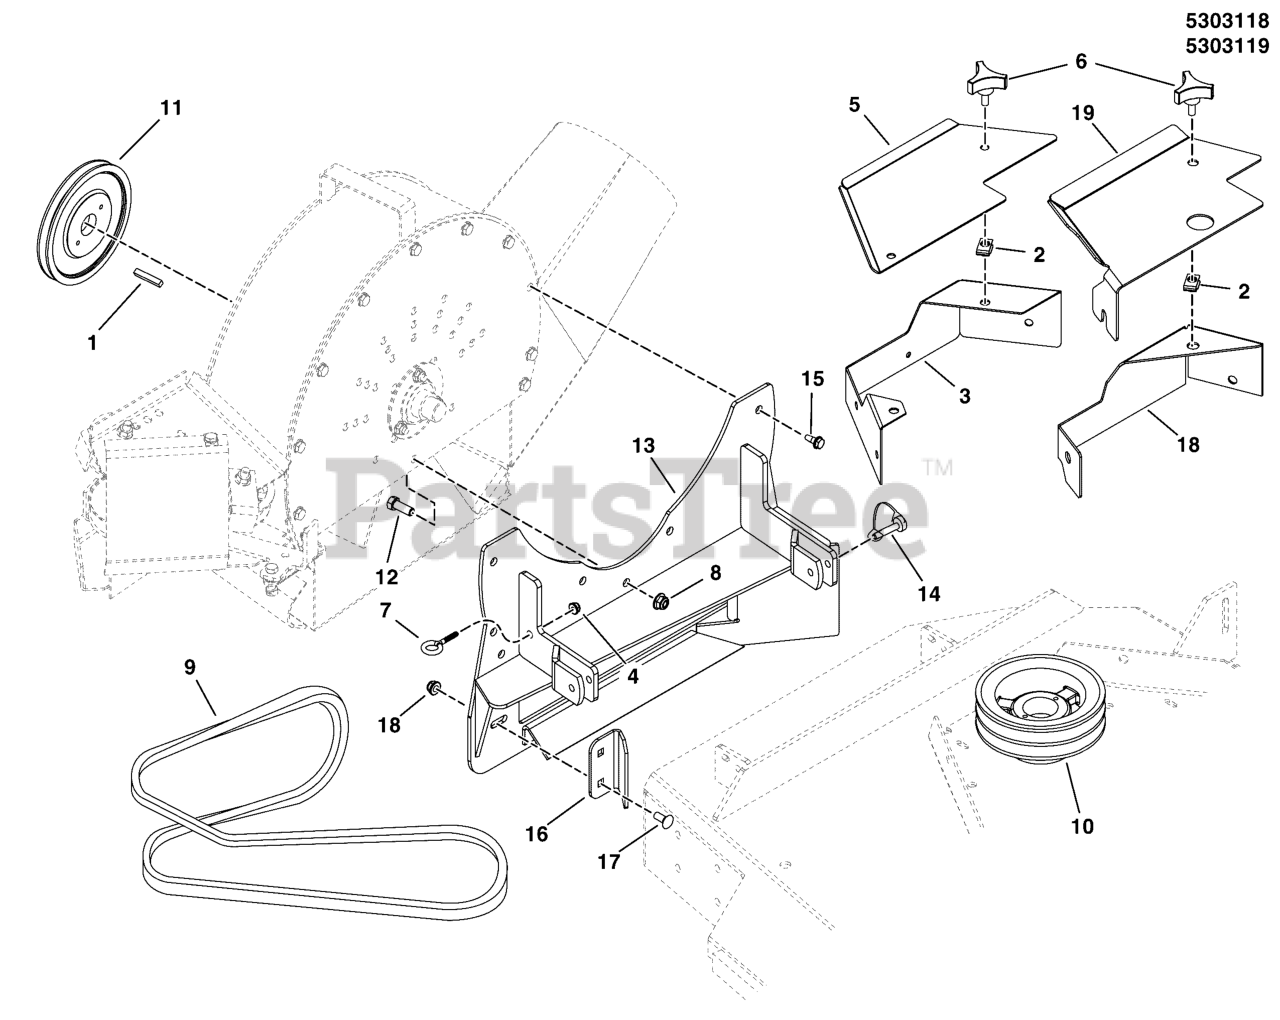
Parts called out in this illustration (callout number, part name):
1	KEY 1/4 SQ X 1 1/2 LONG
2	BODY CLIP, 5/16-18-7GA MATERIAL
3	GUARD, DECK 48, 52 - BLK
4	NUT, 1/4-20 HEX NYLOCK FLANGE
5	GUARD, DECK - BLACK
6	KNOB, PLASTIC, 5/16-18 X 3/4
7	EYE BOLT, 1/4-20 X 2.5, 1THRD, .5EYE,CZ
8	NUT, 3/8-16 HEX NYLOCK FLANGE
9	BELT, A-SEC, 92.00EL, ARAMID, WRPD
10	PULLEY-BLOWER 52 DECK
11	PULLEY, BC-46, 4.55 OD X 1.00 ID
12	BOLT, 3/8-16 X 1" GD5 CZ
13	WELD, ADAPTER, 52ICD, FVAC BLK (5302764)
14	SNAPPERPIN, 5/16 X 2
15	BOLT, 5/16-18 X 5/8" SELF LOCK
16	BRACKET,DEFLECTOR PLATE,52iCD 2011 - BLK
17	BOLT, 5/16-18 X 3/4, CARRIAGE
18	NUT, 5/16-18 HEX NYLOCK FLANGE
19	GUARD, DECK, 52/2000 SND - BLK
20	GUARD, BELT, 52/2000 SND - BLK
